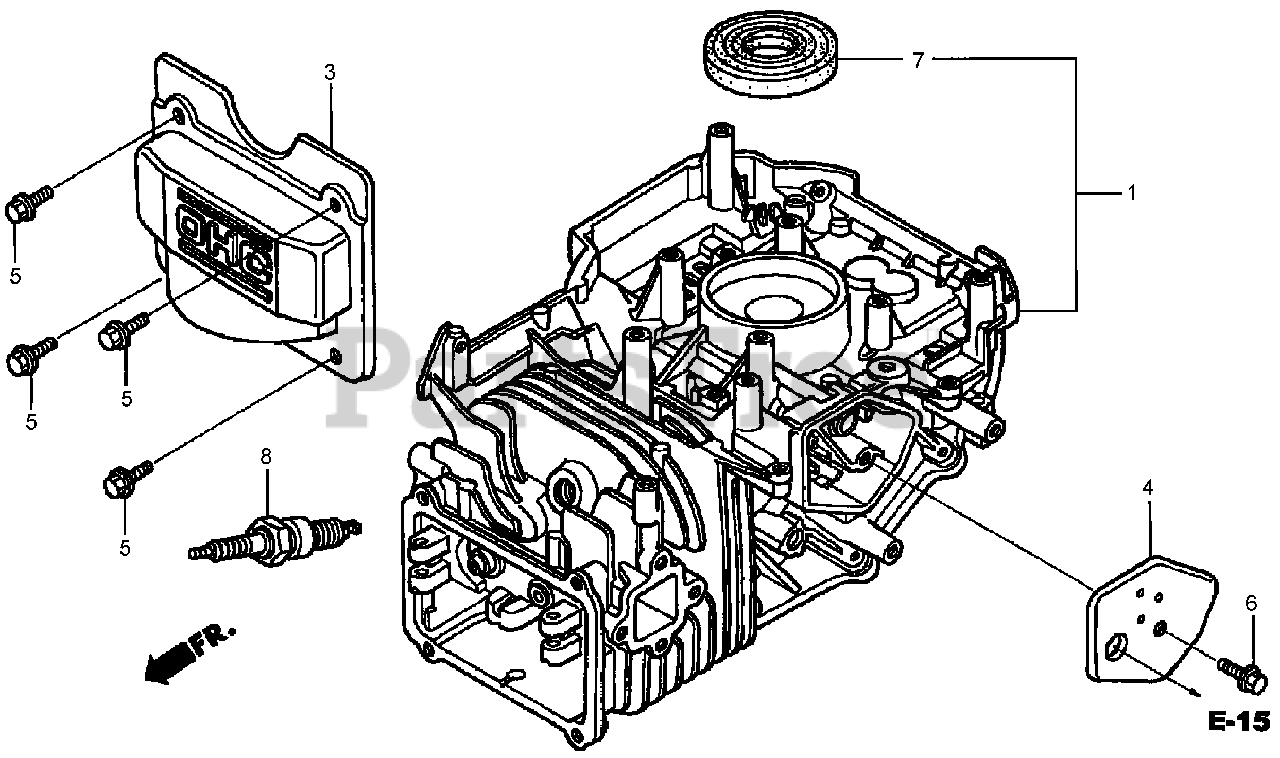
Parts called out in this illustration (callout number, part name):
1	CYLINDER ASM
3	COVER-HEAD
4	COVER-BREATHER (BREATHER VALVE ASM)
5	BOLT-FLANGE (6X12) (CT200)
6	BOLT-FLANGE (6X14)
7	SEAL (25.4X62X6)
8	PLUG-SPARK (BPR6ES) (NGK)
